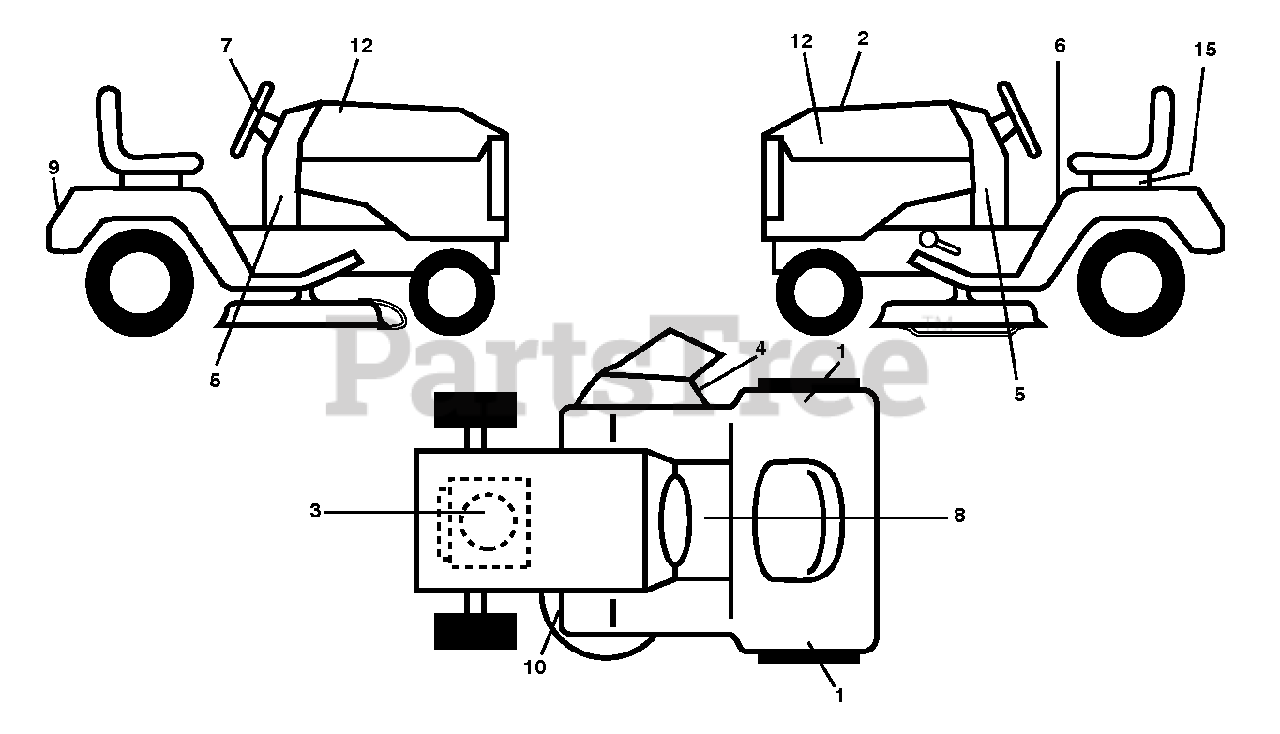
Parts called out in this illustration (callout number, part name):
1	DECAL.FEND.RH/LH.SET.6S.POULAN
2	DECAL.REPLACEMENT.960420144
3	DECAL.ENG.BS.5HP.PB.278978
4	DECAL.WARN.KEEP.HAND.AWAY
5	DECAL.DASH.LWR.17.5/42.POULAN
6	Fender Engine Warning Decal
7	DECAL.WHEEL.STRG.STDHRS.POULAN
9	DECAL.FEND.POULAN.2010
10	DECAL V BELT SCHEMATIC
12	DECAL.HOOD.ALPHA.RH/LH.POULAN
15	DECAL BTRY SYMBOLS
